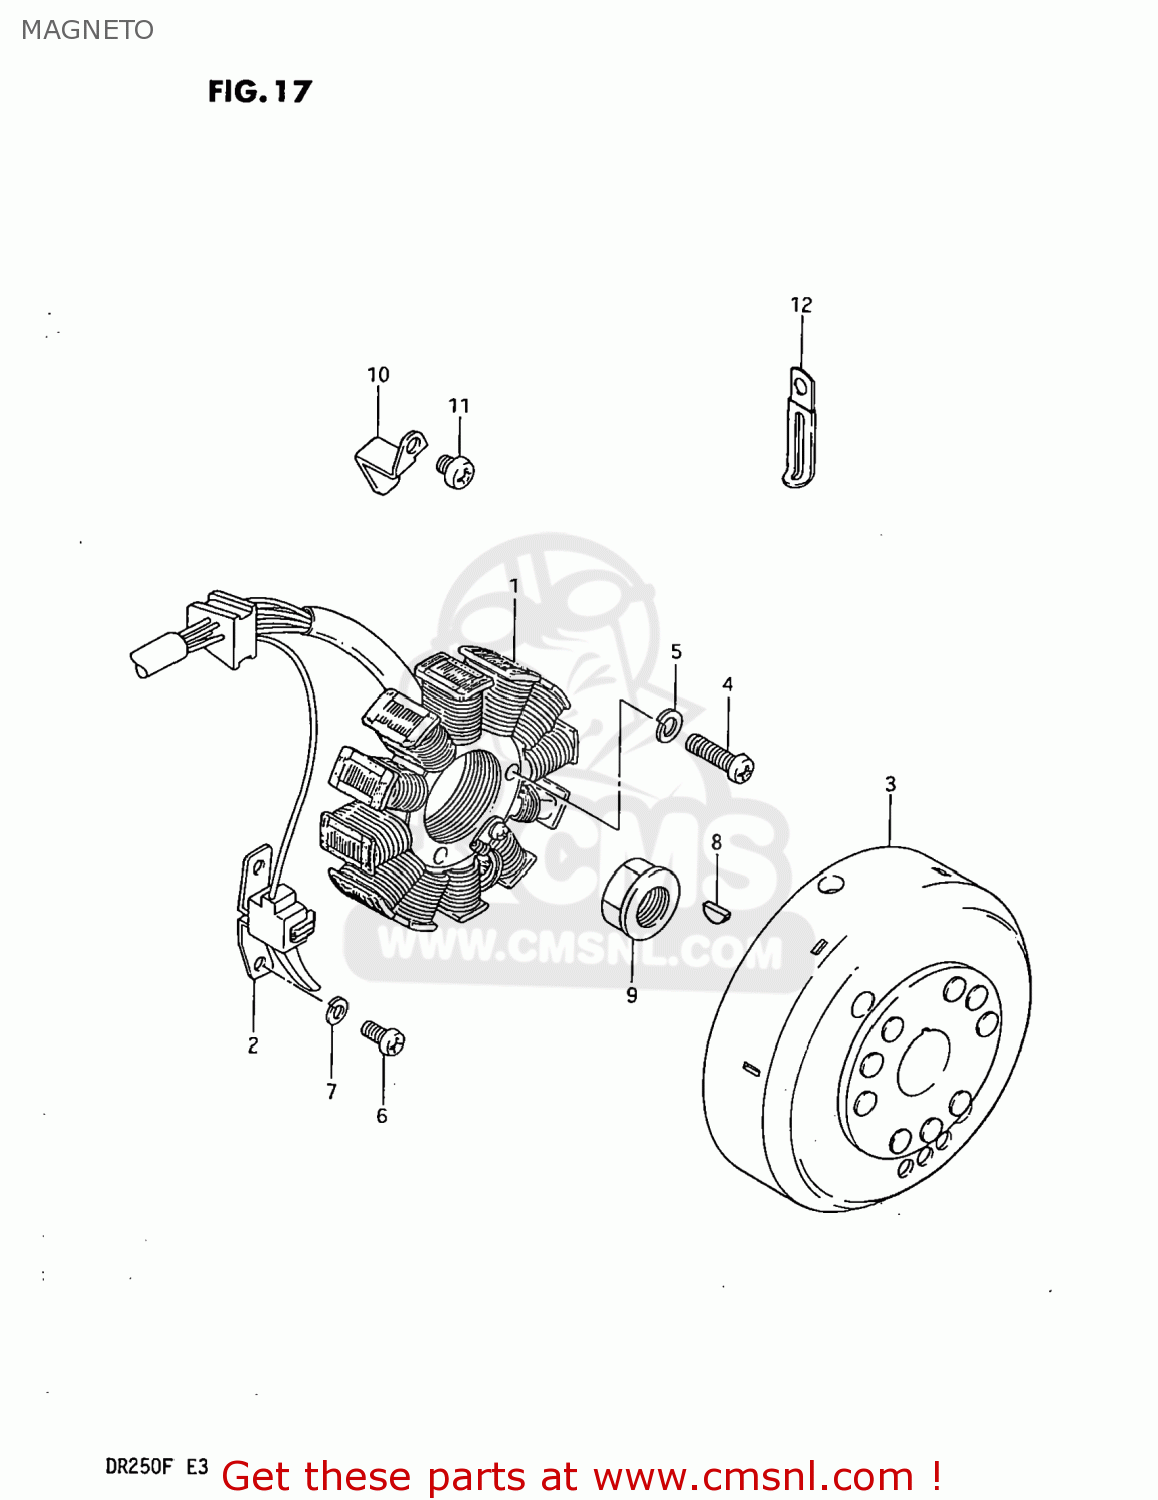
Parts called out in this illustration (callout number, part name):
1	STARTER ASSY
2	COIL,PICK UP
3	ROTOR,FLYWHEEL
4	SCREW
5	LOCK WASHER
6	SCREW
7	LOCK WASHER
8	KEY 4MM
9	NUT,GENERATOR ROTOR
10	CLAMP,MAGNETO LEAD WIRE
11	SCREW
12	CLAMP L:35
